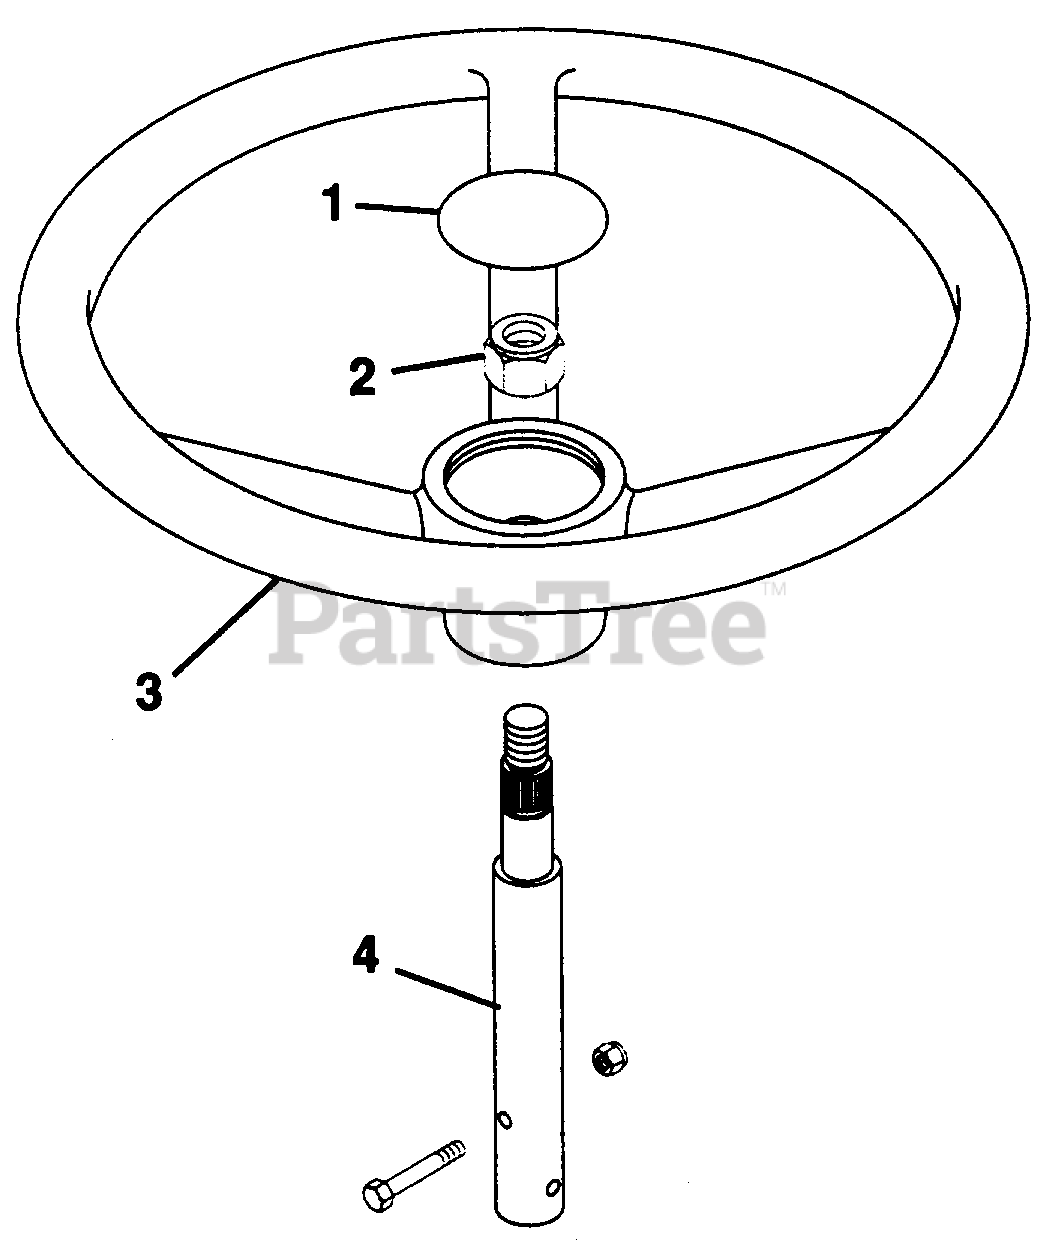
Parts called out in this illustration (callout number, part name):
1	Cap, Steering Wheel
2	Nut, Jam 5/8-11 Hex
3	Wheel, Steering
4	Weldment, Steering Shaft
